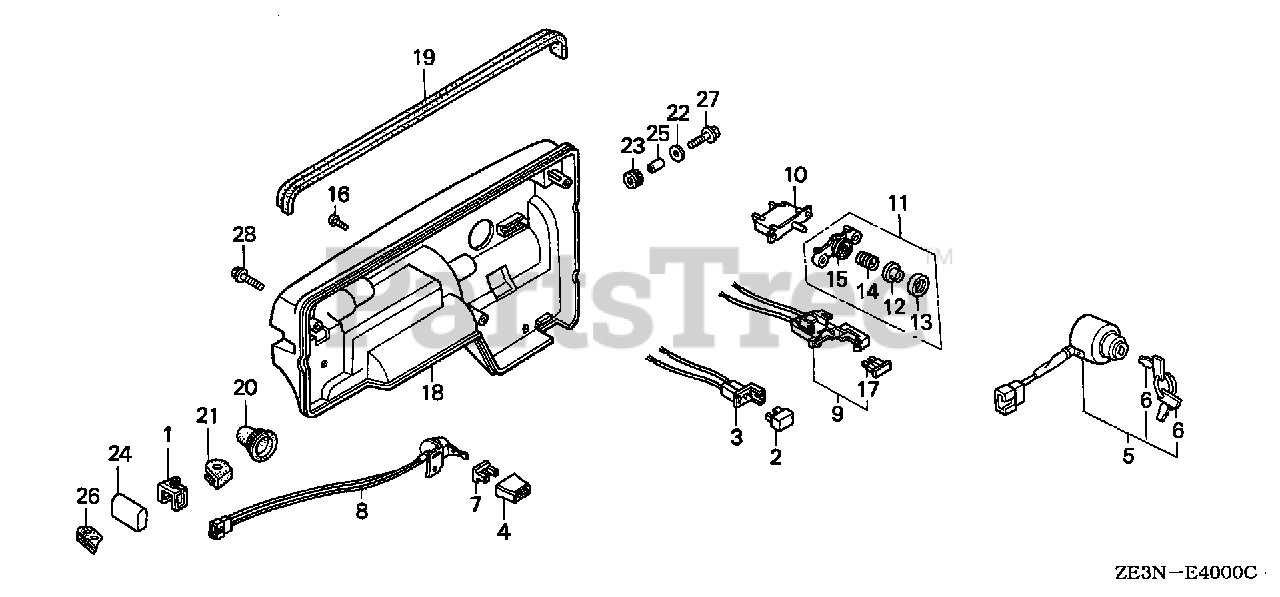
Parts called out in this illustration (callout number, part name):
1	CLIP, WIRE
2	RECTIFIER ASSY., SILICON (STANLEY)
3	CONNECTOR
5	SWITCH ASSY., COMBINATION
6	KEY
9	CASE, FUSE
10	PROTECTOR, CIRCUIT (1.0A)
11	LENS ASSY., PROTECTOR
12	LENS
13	CAP, LENS
14	SPRING, COIL
15	HOLDER, LENS
16	SCREW, GLOVE BOX
17	FUSE, BLADE (5A)
18	CASE, CONTROL *T68* (TSURUI BLUE)
19	RUBBER, CONTROL
20	GROMMET, MAIN WIRE
21	GROMMET, SWITCH WIRE
22	WASHER, FLAT (20MM)
23	RUBBER, CONTROL BOX
24	TUBE, WIRE
25	COLLAR, CONTROL BOX
26	GROMMET, TUBE
27	BOLT, FLANGE (6X20)
28	BOLT, FLANGE (6X40)
